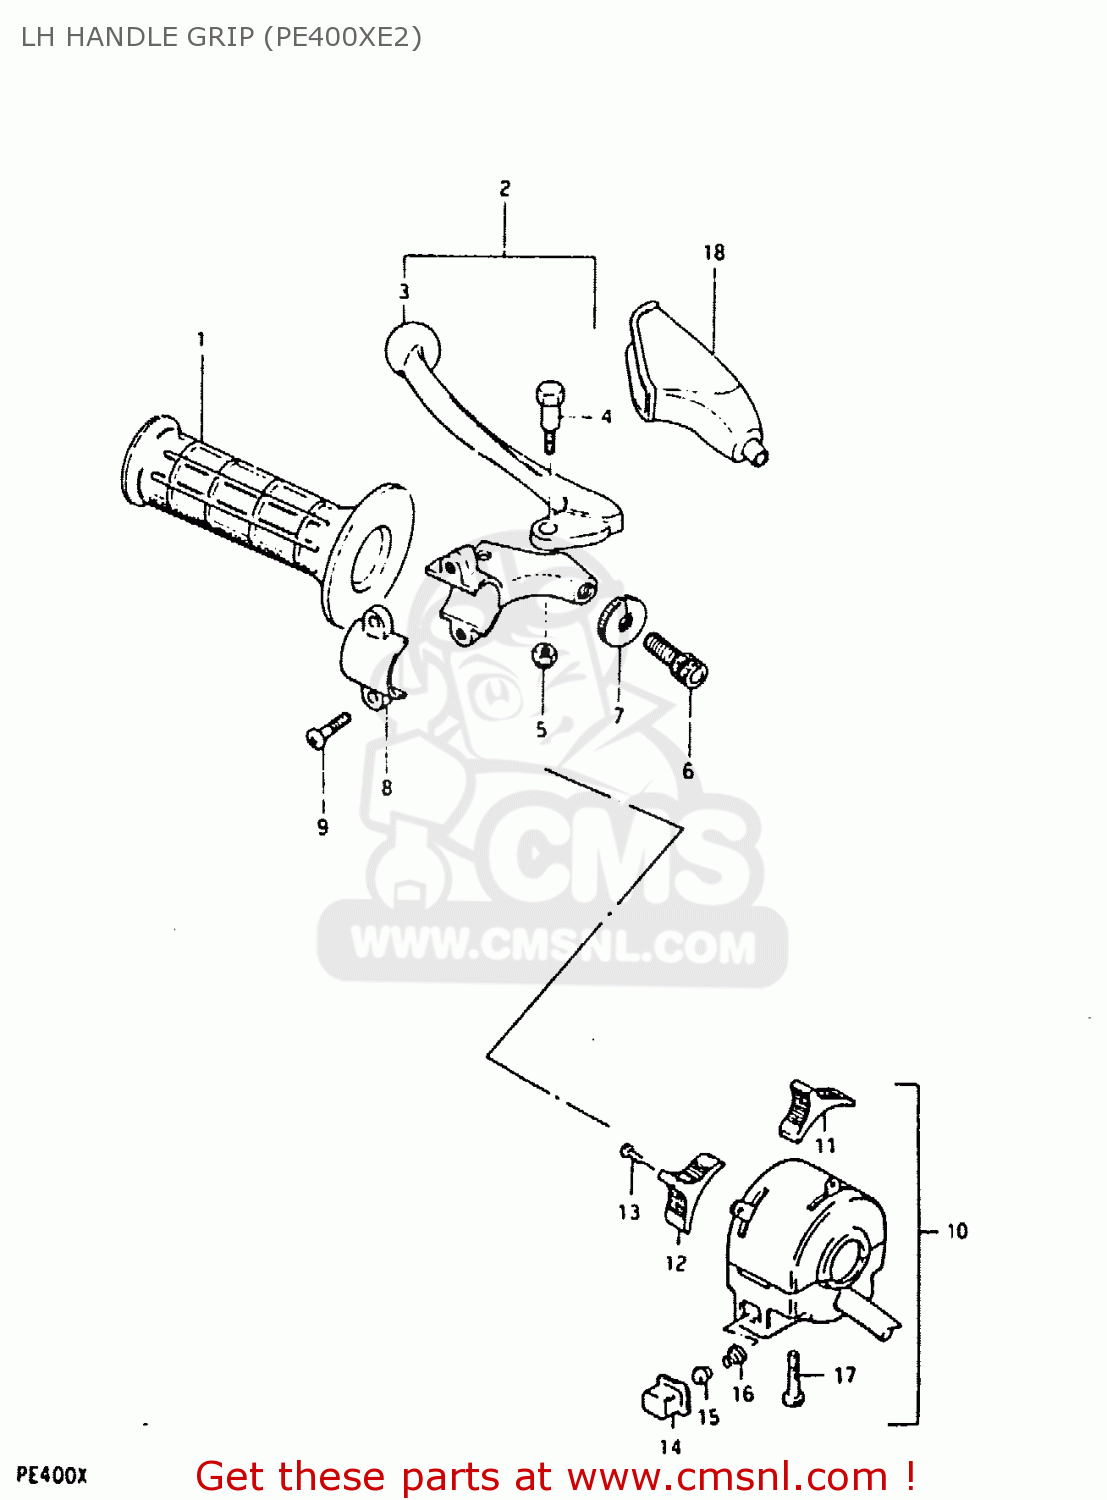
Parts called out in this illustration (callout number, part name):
1	GRIP,LEFT
2	LEVER ASSEMBLY
3	LEVER,CLUTCH
4	BOLT,LEVER
5	NUT 6MM
6	ADJUSTER,CABLE
7	NUT,CABLE ADJUSTER
8	BRACKET,LEVER
9	SCREW
10	SWITCH ASSY, HANDLE LH
11	KNOB,LIGHTING SWITCH
12	KNOB,DIMMER SWITCH
13	SCREW
14	BUTTON,HORN
15	CONTACT
16	SPRING
17	SCREW
18	COVER,CLUTCH LEVER
